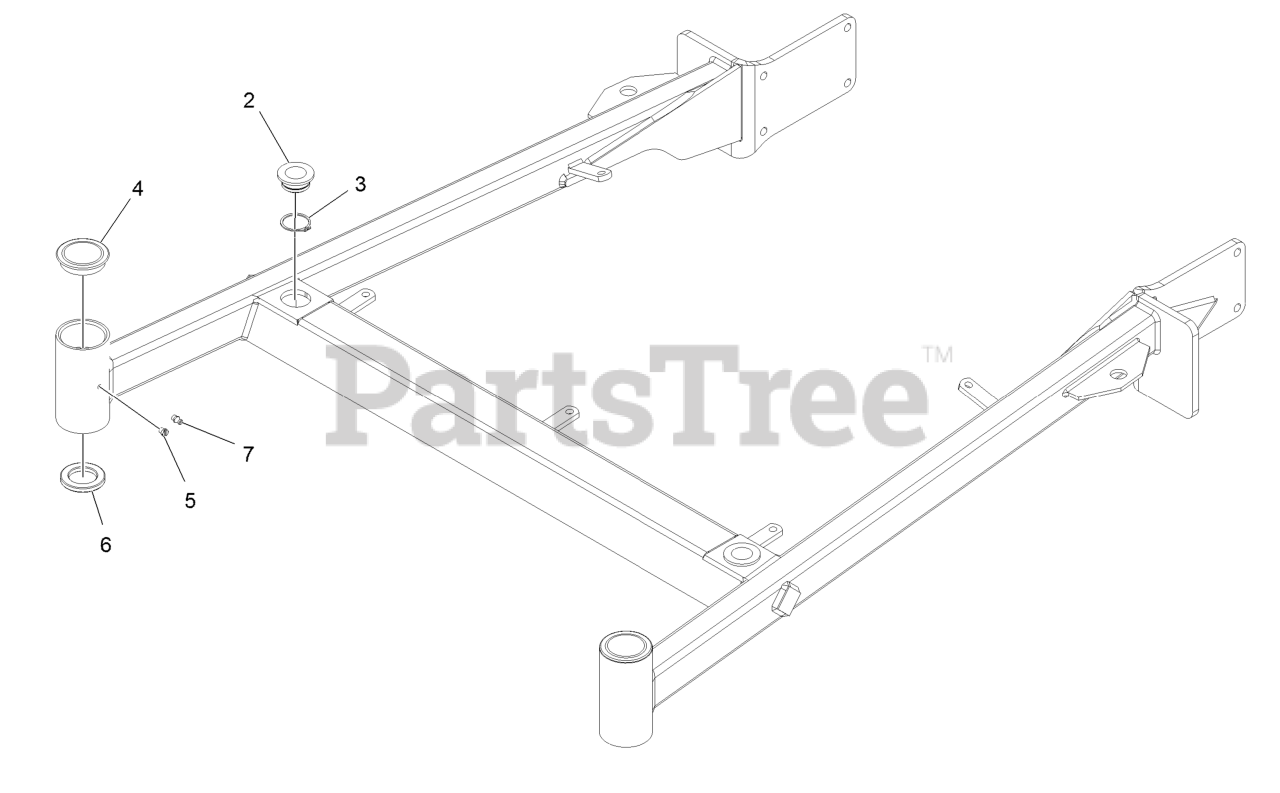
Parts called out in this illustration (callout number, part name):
2	Bushing-Deck
3	Ring-Retaining
4	Cap-Grease
6	Seal-Grease
7	Zerk-1/4-28 Str
